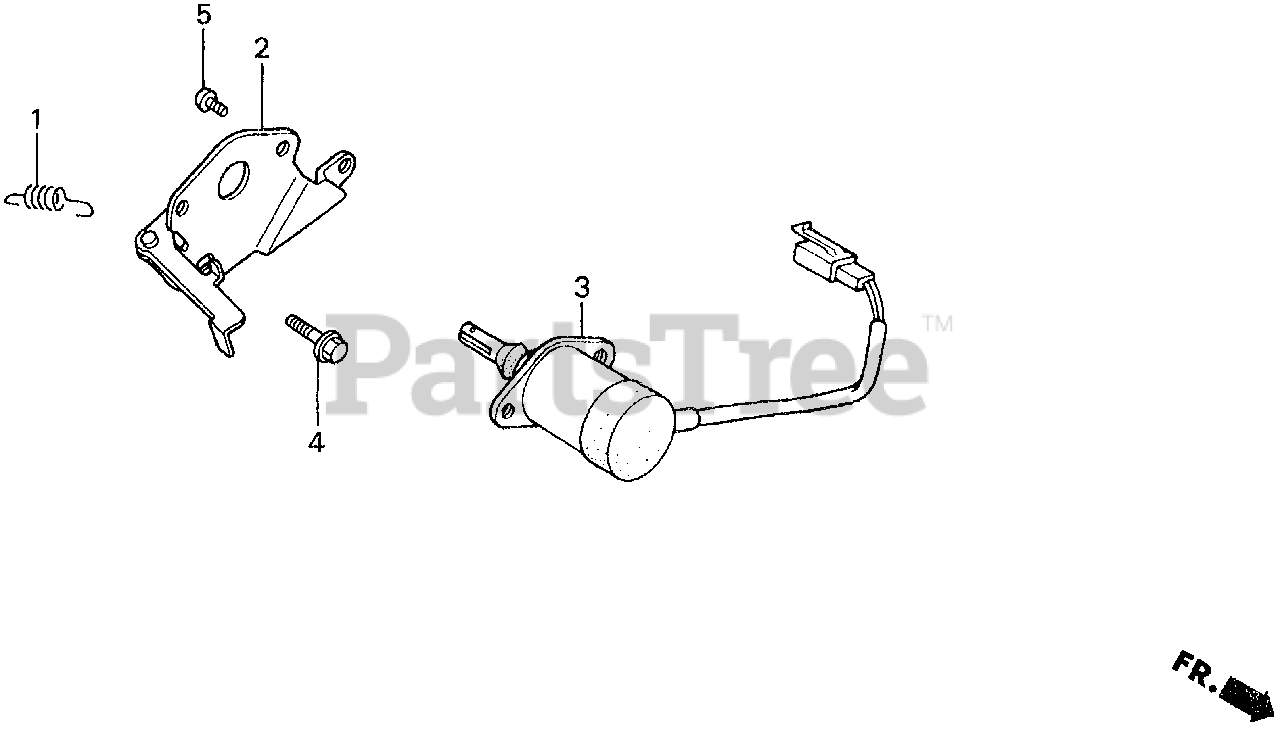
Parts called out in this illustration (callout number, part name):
1	SPRING, CHOKE RETURN
2	LEVER, THROTTLE
3	SOLENOID ASSY.
4	BOLT, FLANGE (6X12) (CT200)
5	SCREW, PAN (5X8)
